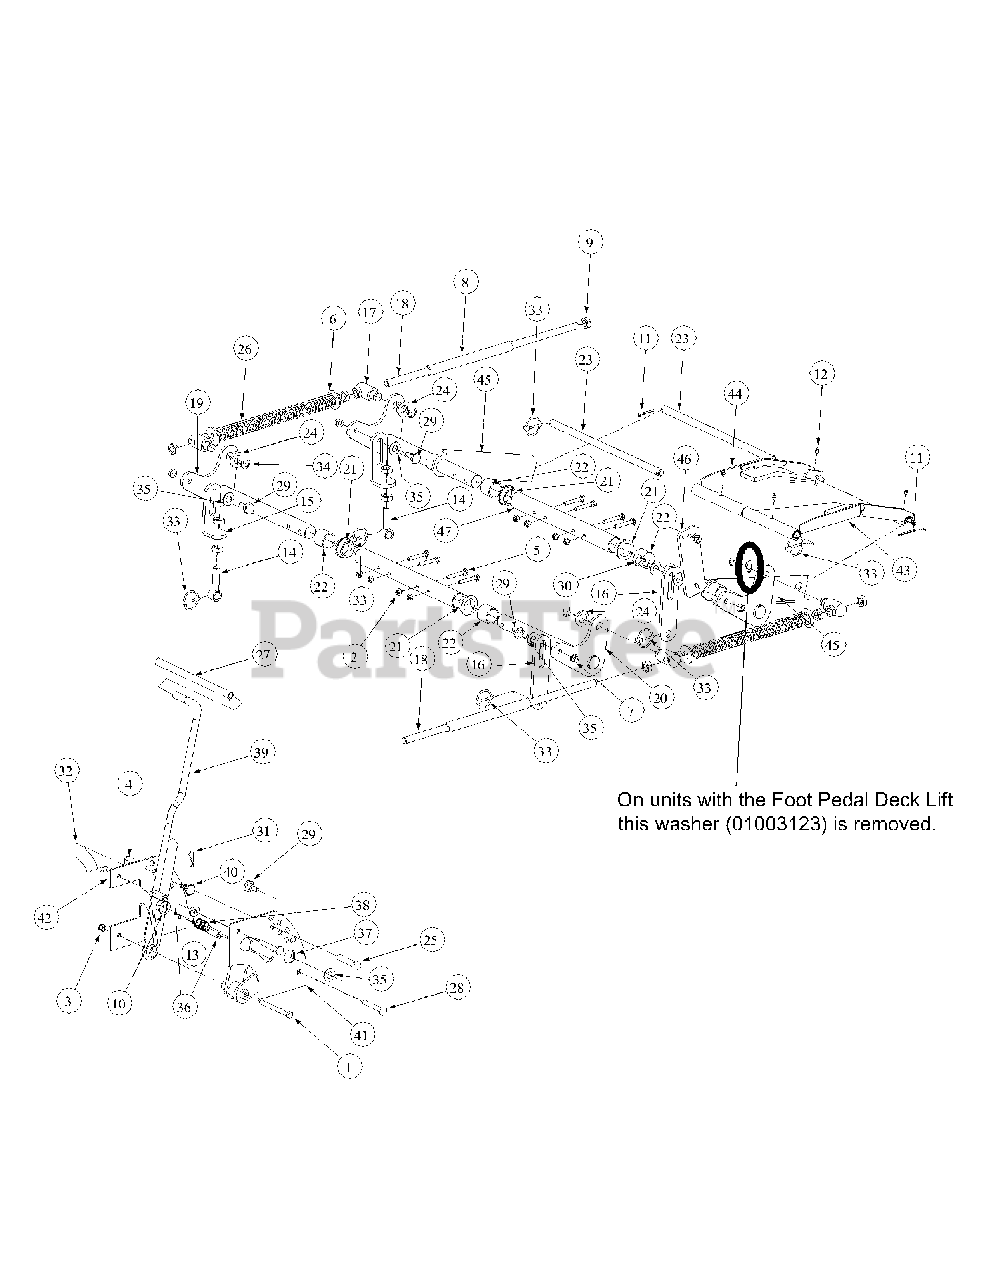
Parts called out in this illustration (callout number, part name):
1	Hex Cap Screw, 3/8-16, 3.75
2	Nut, 5/16-18, Nylock
3	Nylock Insert Lock Nut, 3/8-16
4	Nylock Insert Lock Nut, 1/2-13
5	Hex Cap Screw, 5/16-18 x 2
6	Flat Washer, 5/8
7	Hex Nut, Flange Lock, 3/8-16
8	Hose, 5/8 ID 13/16 OD, 8" LG
9	Jam Nut, 5/8-11
10	Flat Washer, .06, .776, 1.25
11	Cotter Pin, 3/16 x 1-1
12	Grease Fitting, 1/4-28 x 3/16
13	Idler Washer
14	Eye Bolt, 5/8ID
15	Eye Bolt Mount Link, 5/8 ID
16	Deck Link
17	Ferule Lift
18	Lift Connector Rod
19	Bellecrank Weldment Lift, Left Hand
20	Bellecrank Weldment Lift, Right Hand
21	Hex Flange Bearing, 1.25 ID
22	Frame Lift Spacer
23	Front Lift Link, Rod Mount
24	Spacer, .812 ID x .268 Lg.
25	Clevis Pin, .500 Dia. x 2.625 Lg.
26	Lift Compression Spring
27	Lift Handle Grip
28	Carriage Bolt, 3/8-16, 2.75
29	Shoulder Screw, 0.625 OD x .437 Lg.
30	Shoulder Screw, 0.625 OD x .830 Lg.
31	Cotter Pin, .148 x 3.00
32	Decal Height Indicator
33	Linch Pin, 3/16 Dia.
34	E Clip, 3/4 Dia.
35	Nylon Flat Washer, 5/8
36	Spacer, .39 ID x .63 OD x 1.442
37	Lift Pivot Assembly
38	Lift Handle Spring
39	Lift Handle Assembly
40	Shoulder Screw, 5/8 OD x 0.264
41	Outer Lift Index Plate
42	Inner Lift Index Plate
43	Bearing Lift Brace Assembly, Right Hand
44	Bearing Lift Brace Assembly, Left Hand
45	Front Frame Strut Assembly
46	Lift Link Adjustment
47	Lift Shaft Holder
